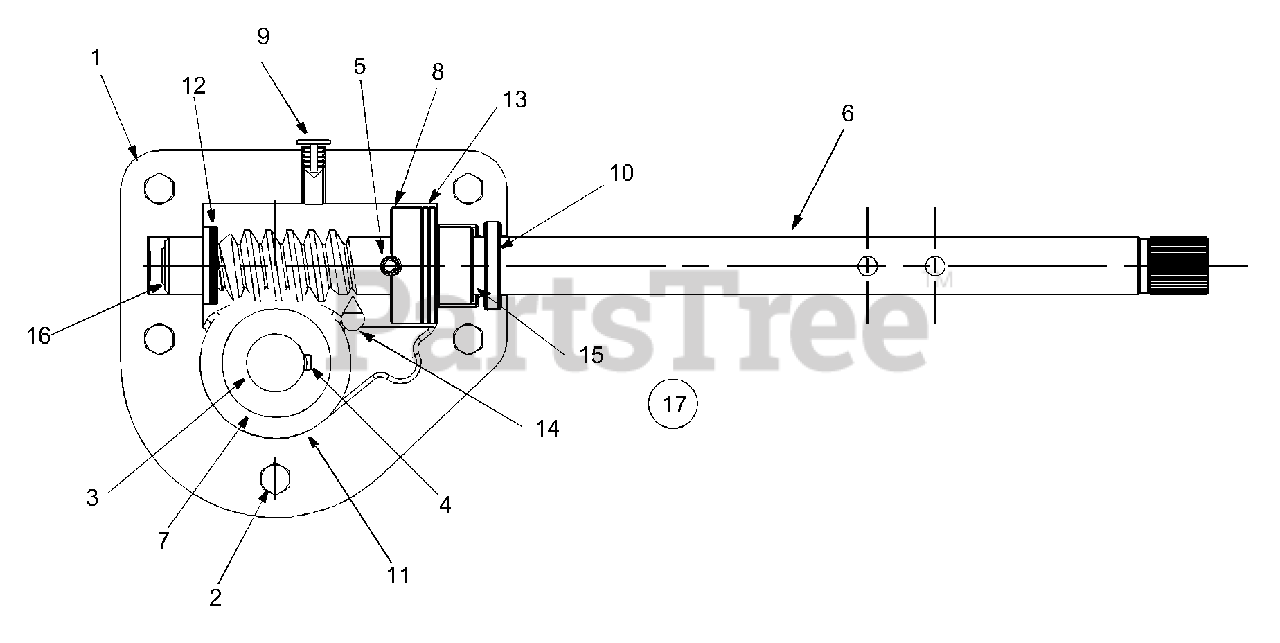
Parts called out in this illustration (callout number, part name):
1	Housing - L.H.
2	Hex Screw 1/4-20 x .75
3	Spiral Axle 26"
4	Key
5	Pin-Spiral
6	Shaft-Worm
7	Gear-Worm
8	Collar-Thrust
10	Seal-Oil
11	Washer-Flat
12	Washer-Flat
13	Washer-Flat
14	Grease
15	Bearing-Flange
16	Bearing-Flange
17	Ass'y. Complete 26"
